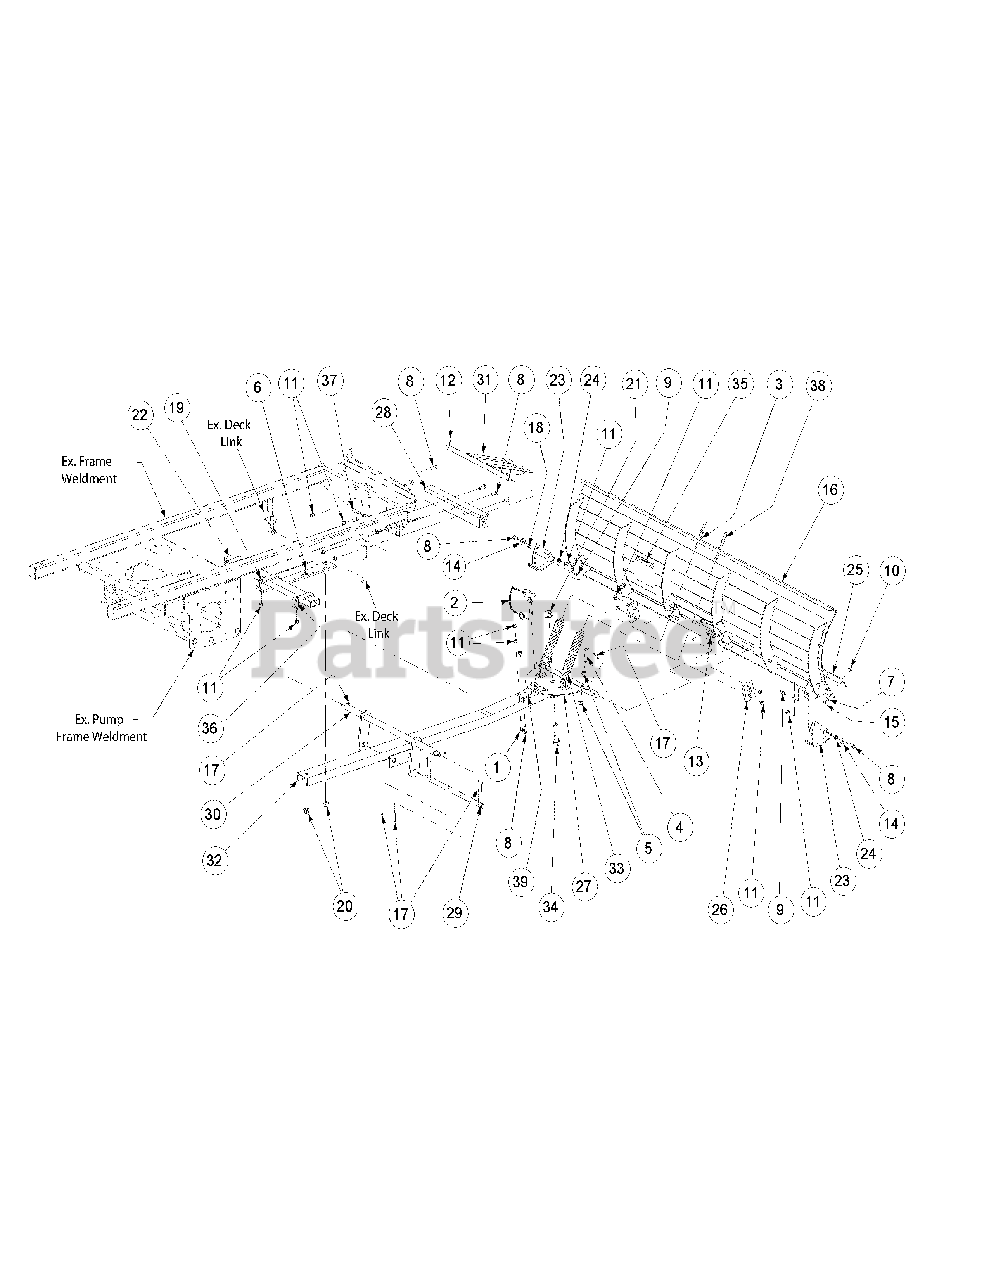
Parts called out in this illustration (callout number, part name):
1	Hex Cap Screw:3/8-16 x 1.75
2	Sulky Pin
3	Hex Nut 3/8-16
4	Hex Cap Screw:1/2-13 x 2.0
5	Hex Nut:1/2-13
6	Hex Cap Screw:1/2-13 x 1.50
7	Washer:5/16
8	Hex Cap Screw:3/8-16 x 1.0
9	Clevis Pin:5/16 x 1.0
10	Carriage Bolt:5/16-18 x .75
11	Flange Lock Hex Nut, 3/8-16
12	Cotter Pin:1/8 x 1.0:SS
13	Hex Cap Screw, 3/8 -16 x 1.25
14	Washer, .385 x 1.0 OD x .135
15	Hex Flange Lock Nut, 5/16-18
16	Snow Blade Weldment
17	Cotter Pin, 5/32, 1.25
18	Cotter Pin, .072 x 1.12 Lg
19	Hex Cap Screw:3/8-16 x 2.0
20	Flange Lock Nut, 1/2-13
21	Nut, 3/4-16, Hex Flange
22	Rear Support Weldment
23	Skid Plate Weldment
24	Skid Plate Spacer
25	Snow Blade
26	Rod Bearing Pivot Plate
27	Pivot Blade Weldment
28	Front Stabilizer Bracket Weldment
30	Lift Rod Weldment
31	Bracket Guide Weldment
32	Channel Support Weldment
33	Spring, Blade Adjust
34	Hex Cap Screw, 3/8-16 x 3.00
35	Label, Warning
36	Rear Support Spacer
37	Front Stabilizer Plate
38	Bolt:3/8-16 x 4.50
39	Retainer Pin Bracket
